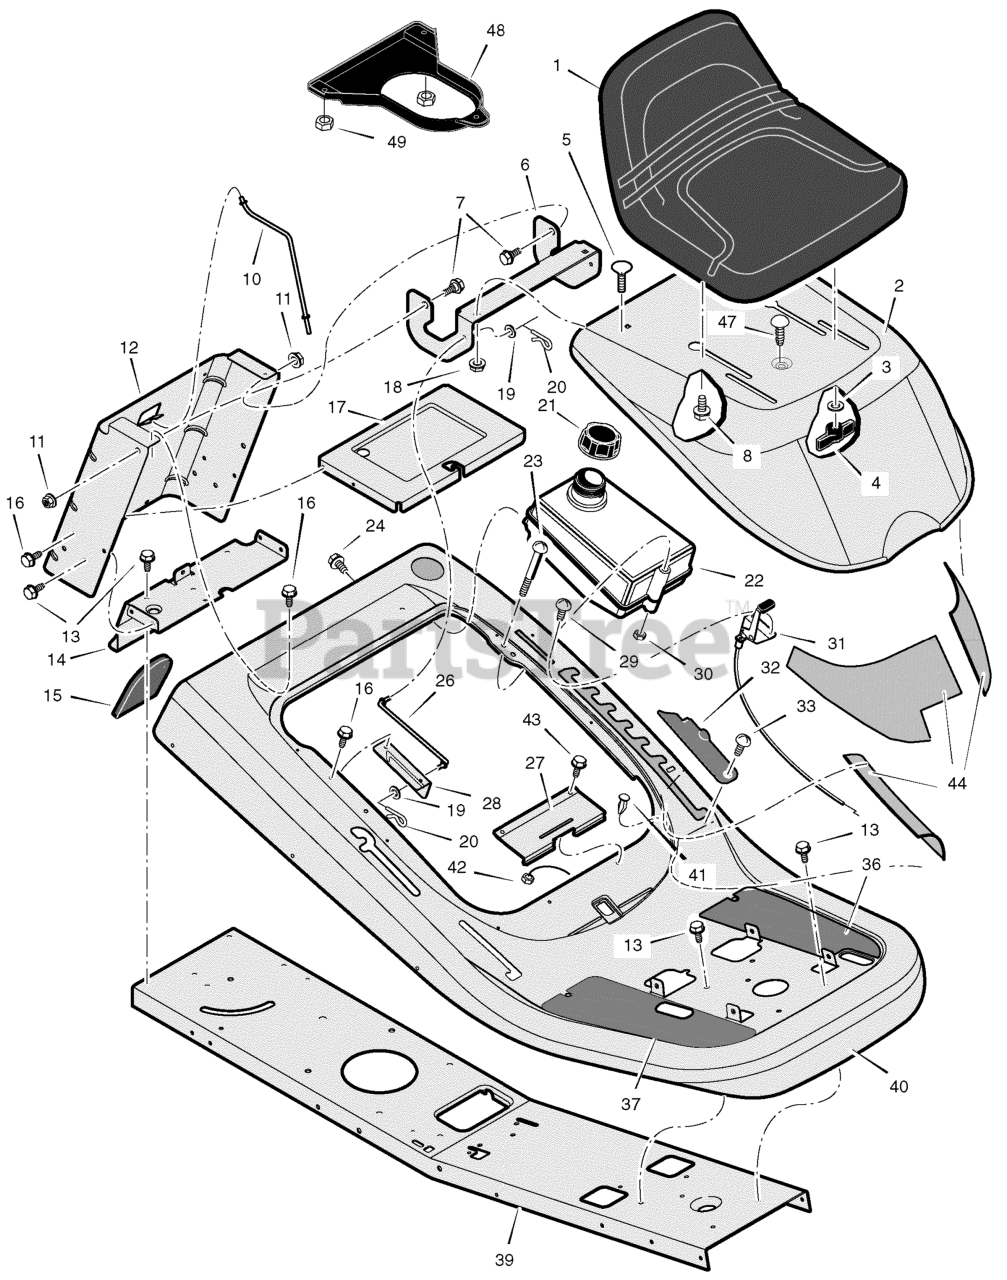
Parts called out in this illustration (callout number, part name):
3	Washer
4	Bolt, Wing
5	Bolt, Carriage
6	Bracket, Hinge
7	Bolt, Shoulder
8	Bolt, Shoulder
10	Rod, Battery
11	Nut, Flange
12	Plate, Rear
13	Screw
14	Plate, Hitch
16	Screw
17	TRAY, Battery
18	Nut, Flange
19	Washer
20	Pin, Cotter
21	Cap, Fuel Tank
22	Tank, Fuel
26	Rod, Hood Prop
27	Spring, Seat Deck
28	Bracket, Prop Rod
29	Screw
30	Nut, NY-Lock
31	Control, Throttle
32	Cover, Detent (Black)
33	Bolt, Shoulder
36	Footmat, Left
37	Footmat, Right
40	Deck, Seat
41	Bumper
43	Screw
44	Kit, Foil Heat Shield
47	Fastener, Panel
49	Nut, Hex 5/16-18
